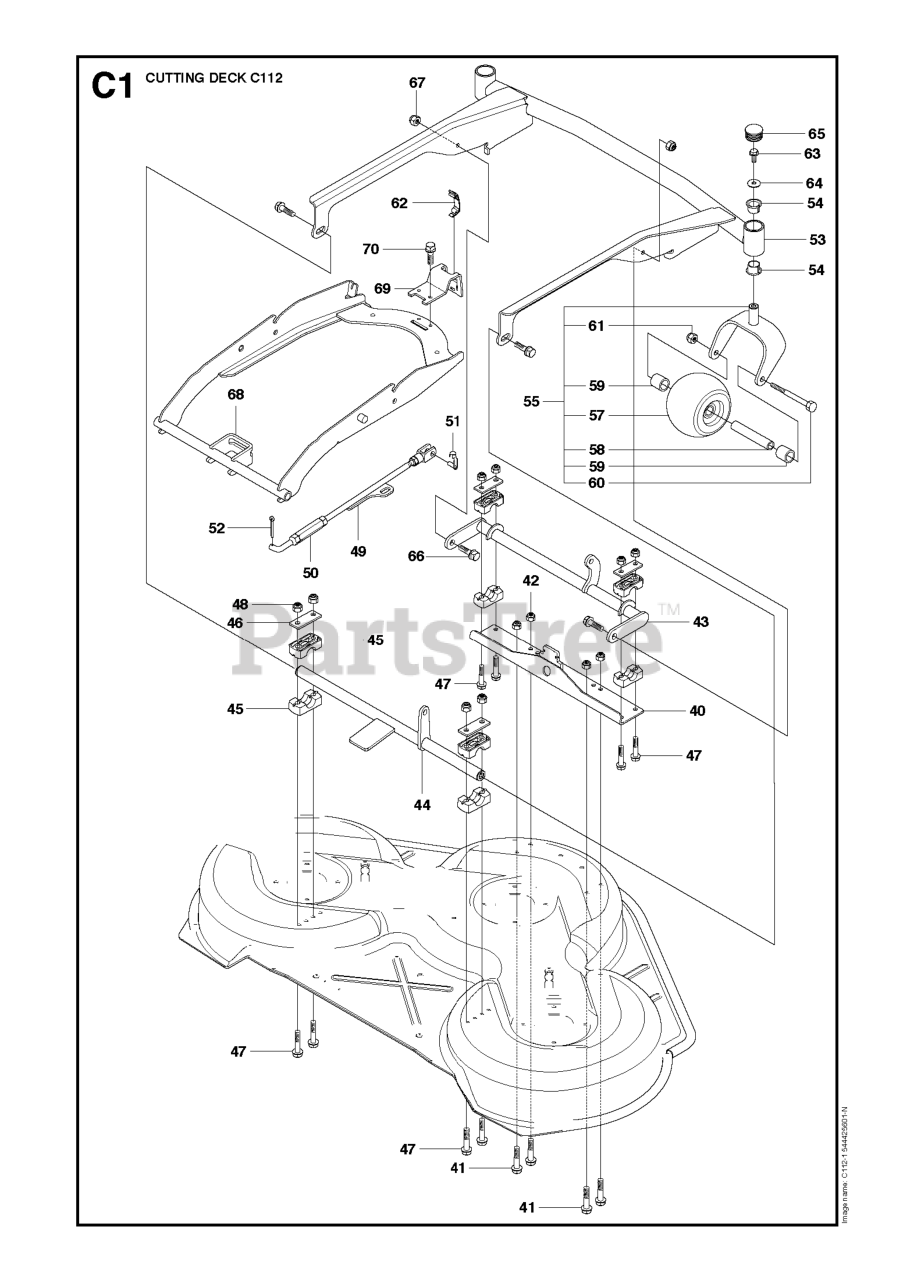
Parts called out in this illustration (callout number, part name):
1	CHASSIS STAMPING
2	DRAWBAR, 12GA
3	SCREW 3/8-16X3/4
5	BUMPER.RUBBER.HOOD
10	BOLT D
11	PANEL.DASH.LH.LTX
13	PANEL ASM, DASH RH
17	VENT.HOOD.LASER.III
18	BUMPER.HOOD.LARGE.1.75"
26	NUT
30	FENDER STL W/CUPHOLDER
31	BRACKET.SUPPORT.FENDER
37	Screw 5/16-18 x 1/2 Hex, Self Tapping 5/16-18 x 1/2
38	BRACKET.ASM.PIVOT.MOWER.REAR
39	BRACKET PIVOT LASER
60	Bolt - Rd. Hd. Sq. Neckiage 3/8 16 x 3/4
64	DASH LOWER
90	NUT.PUSH.3/16
142	PLATE REINFORCEMENT
143	BRACKET, SWAYBAR CHASSIS
144	BRKT, FOOT REST
145	ROD PIVOT CHASSIS/HOOD
159	GREY CUP HOLDER
166	SCREW
206	SHOULDER BOLT 5/16-18TT
207	SCREW, 5/16-18 X 1/2
208	SCREW 3/8-16X1/2
209	SCREW, 3/8-16X3/4
212	INSERT.LENS.REFLECTIVE
217	CONSOLE FUEL WINDOW
258	LENS LH
259	LENS LH
260	COVER.LENS.HUSQ.LASER
272	VENT.HOOD.LASER.
273	VENT.HOOD.LASER.
